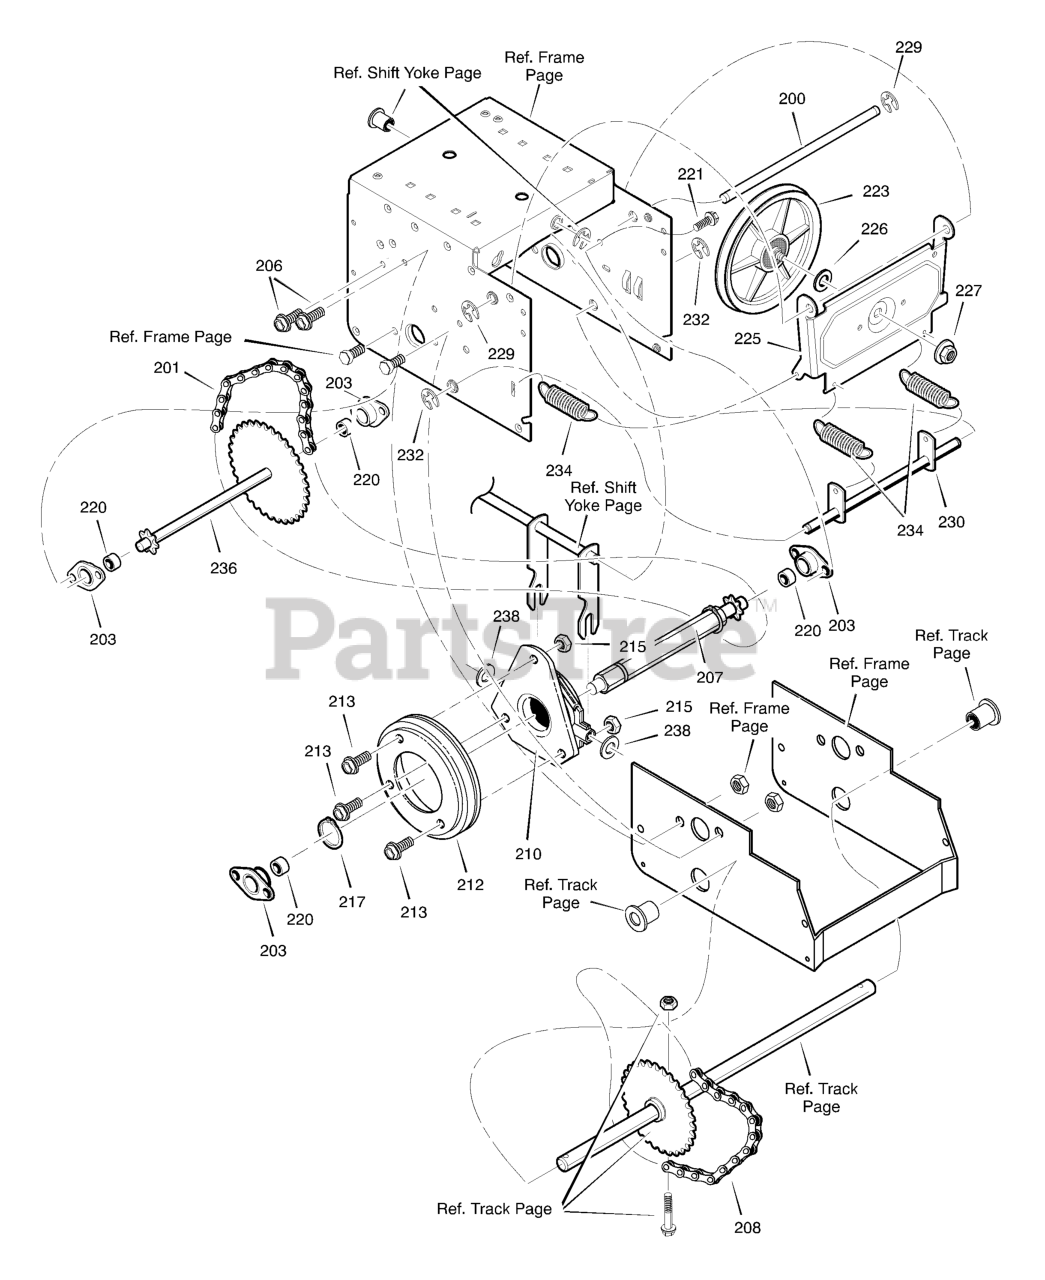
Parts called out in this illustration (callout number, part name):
200	LF AXLE, SWING PLATE YZ
201	CHAIN, ROLLER #42x19.00 LG
203	RETAINER, BEARING
206	SCREW, TAP 5/16-18 x 0.5
207	ASSY, HEX SHAFT
208	CHAIN, ROLLER
210	BEARING, TRUNION CLUTCH R
212	Track, FRICTION DISC
213	SCREW, 1/4-20 x 0.63
215	NUT, KEPS HEX 1/4-20
217	RING, RETEXT
220	BEARING, BALL
221	SCREW, TAP 5/16-18 X .50
223	ASSY, FRICTION PULLY
225	LF PLATE, SWINGING YZ
226	SPACER, FRICTION PULLEY
227	NUT, FLANGE LOCK 3/8-24
229	RETAINER, RING
230	LF ASSY, SPRING LINK YZ
232	RETAINER, RING
234	SPRING, EXTENSION
236	WLD, INTERMED SPROCKET
238	WASHER, FLAT
